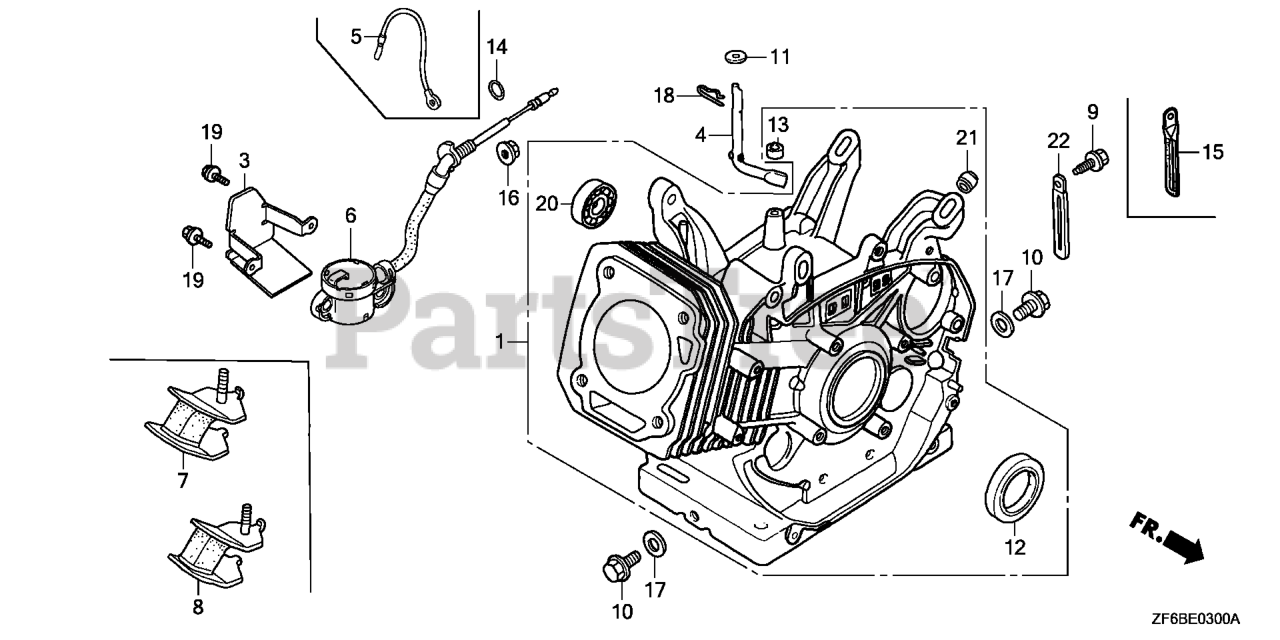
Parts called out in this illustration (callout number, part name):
1	CYLINDER ASSY. (ALERT)
4	SHAFT, GOVERNOR ARM
6	SWITCH ASSY., OIL LEVEL
10	BOLT, DRAIN PLUG
11	WASHER (8.2X17X0.8)
12	OIL SEAL (35X52X8) (NOK)
13	OIL SEAL (8X14X5)
14	O-RING (14MM) (ARAI) Use up to Engine SN 2949254.
16	NUT, FLANGE (10MM)
17	WASHER, DRAIN PLUG (12MM)
18	PIN, LOCK (10MM)
19	BOLT, FLANGE (6X12) Use up to Engine SN 1543277.
20	BEARING, RADIAL BALL (6202)
